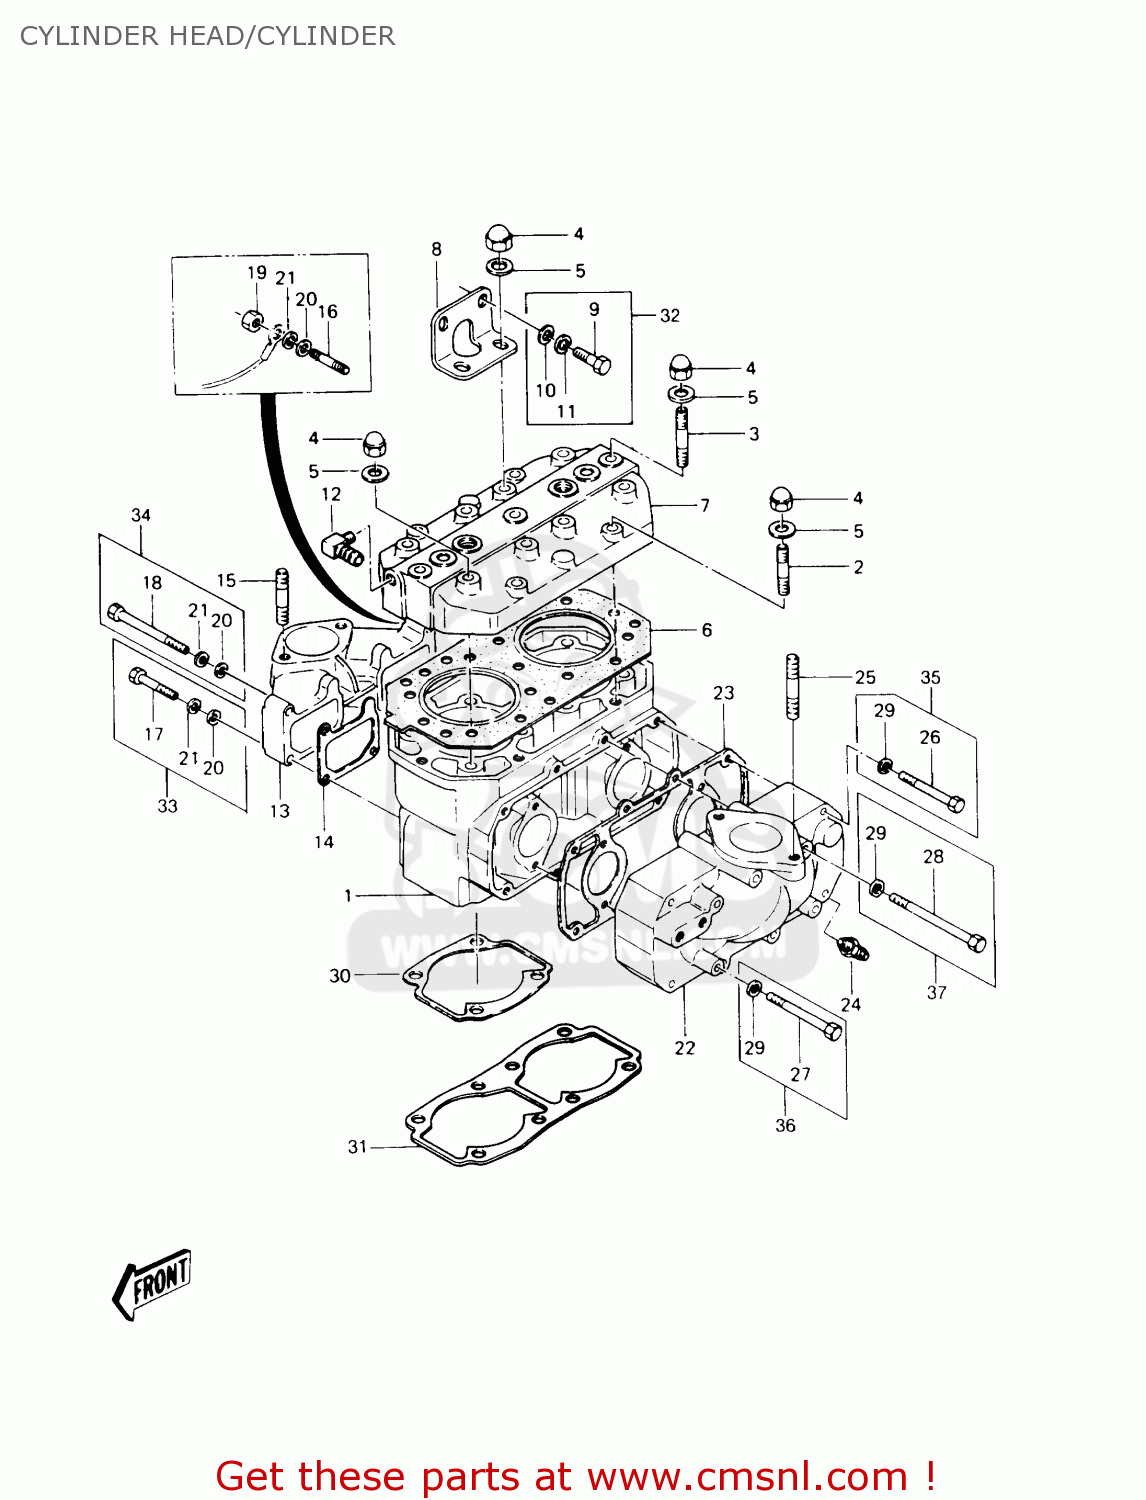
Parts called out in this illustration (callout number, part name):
1	CYLINDER-ENGINE
2	STUD,8X42
3	STUD,8X50
4	NUT,CAP,8MM
5	WASHER
6	GASKET-HEAD (MCA)
7	HEAD-COMP-CYLINDER
8	BRACKET
9	BOLT 6X14
10	WASHER
11	WASHER-SPRING,6MM
12	ELBOW-WATER HOSE
13	MANIFOLD-INTAKE
14	GASKET,INTAKE (MCA)
15	STUD,8X35
16	STUD,6X35
17	BOLT 6X35
18	BOLT,6X70
19	NUT,6M/M
20	WASHER-PLAIN-SMALL,6M
21	WASHER-SPRING,6MM
22	MANIFOLD-EXHAUST
23	GASKET,EXHAUST (MCA)
24	JOINT,HOSE
25	STUD,8X35
26	BOLT,6X50
27	BOLT,6X70
28	BOLT,6X85
29	WASHER-PLAIN-SMALL,6M
30	GASKET,CYLINDER (MCA)
